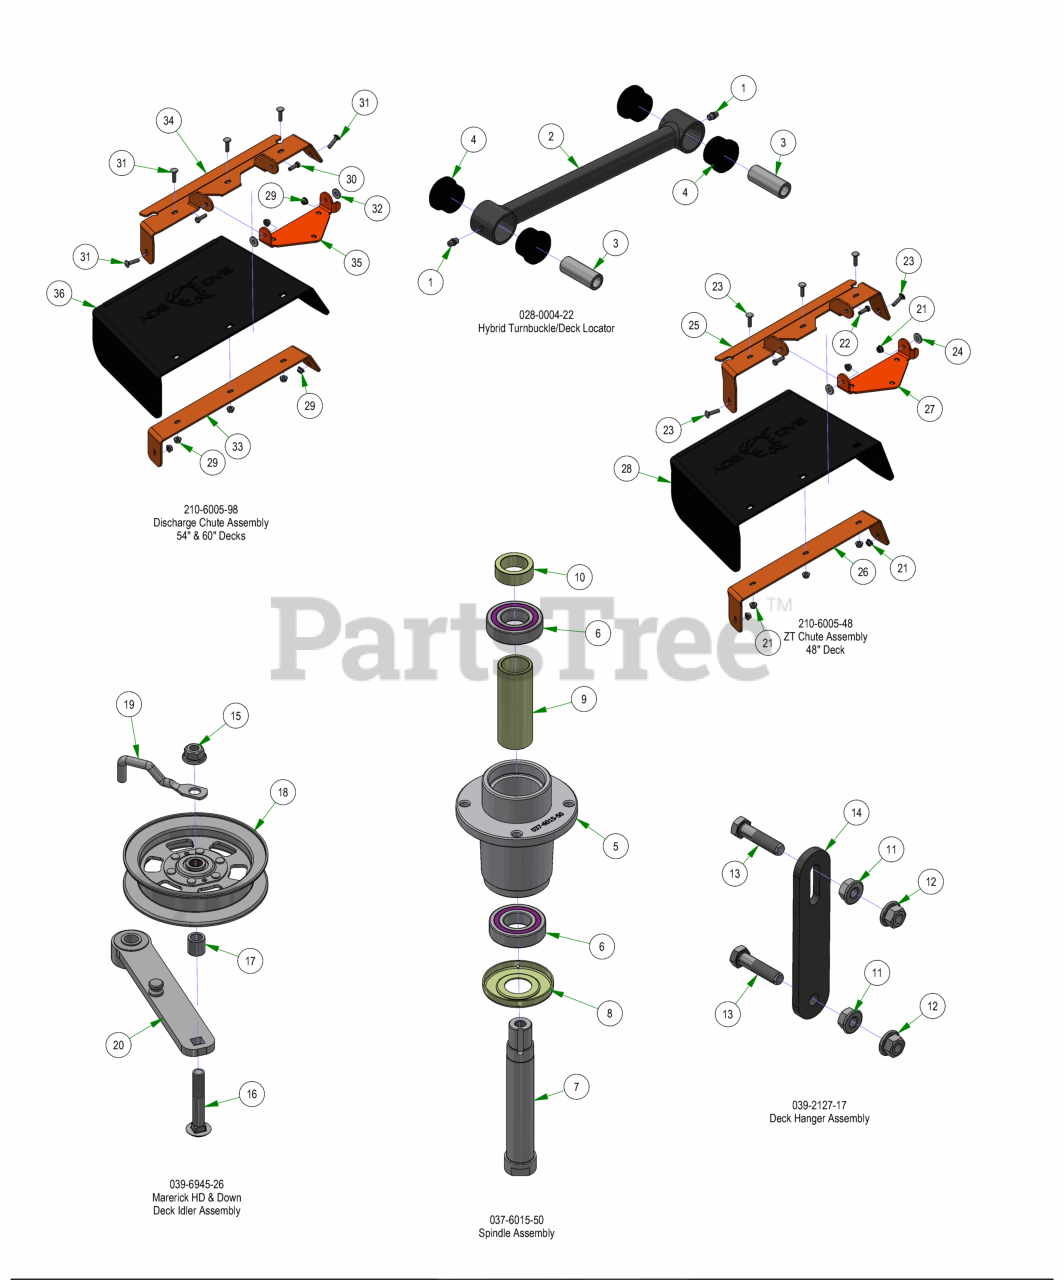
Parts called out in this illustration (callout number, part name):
1	1/4-28 Grease Fitting
2	2022 Isolator Turnbuckle Body
3	2018 Maverick Bushing Sleeve
4	2018 Maverick Bushing
5	Spindle Housing
6	Bearing - 6206
7	Spindle Shaft
8	Spindle Dust Cap
9	Spindle Spacer
10	Locking Collar w/ 1/4"-20 Set Screw
11	3/8-16 HEX SERRATED FLANGE NUT HARD/ZINC
12	3/8-16 NYLON INSERT FLANGE LOCKNUT (GR.F) ZINC
13	3/8-16 X 1-1/2 HEX CAP SCREW (GR.5) ZINC
14	2017 MZ/ZT Deck Hanger
15	1/2-13 NYLON INSERT FLANGE LOCKNUT ZINC
16	1/2-13 x 3 Carriage Bolt Grade 5
17	.51 ID X .75 OD X .75 LGTH SOLID SPACER ZINC
18	5" Idler Pully
19	2025 R-Series Belt Retainer
20	2025 Tensioner Arm With Bearings
21	5/16-18 NYLON INSERT FLANGE LOCKNUT ZINC
22	5/16-18 X 1 HEX CAP SCREW (GR.5) ZINC
23	5/16-18 X 1-1/4 CARRIAGE BOLT ZINC
24	.360 ID X .983 OD X .120 THICK FLAT WASHER NYLON
25	Discharge Upper Chute Bracket
26	Discharge Lower Chute Bracket
27	Discharge Chute Hanger (deck mounted)
28	Rubber Discharge Chute
29	5/16-18 NYLON INSERT FLANGE LOCKNUT ZINC
30	5/16-18 X 1 HEX CAP SCREW (GR.5) ZINC
31	5/16-18 X 1-1/4 CARRIAGE BOLT ZINC
32	.360 ID X .983 OD X .120 THICK FLAT WASHER NYLON
33	60" Discharge Lower Bracket
34	60" Discharge Chute Upper Hanger
35	Discharge Chute Hanger (deck mounted)
36	Rubber Discharge Chute
